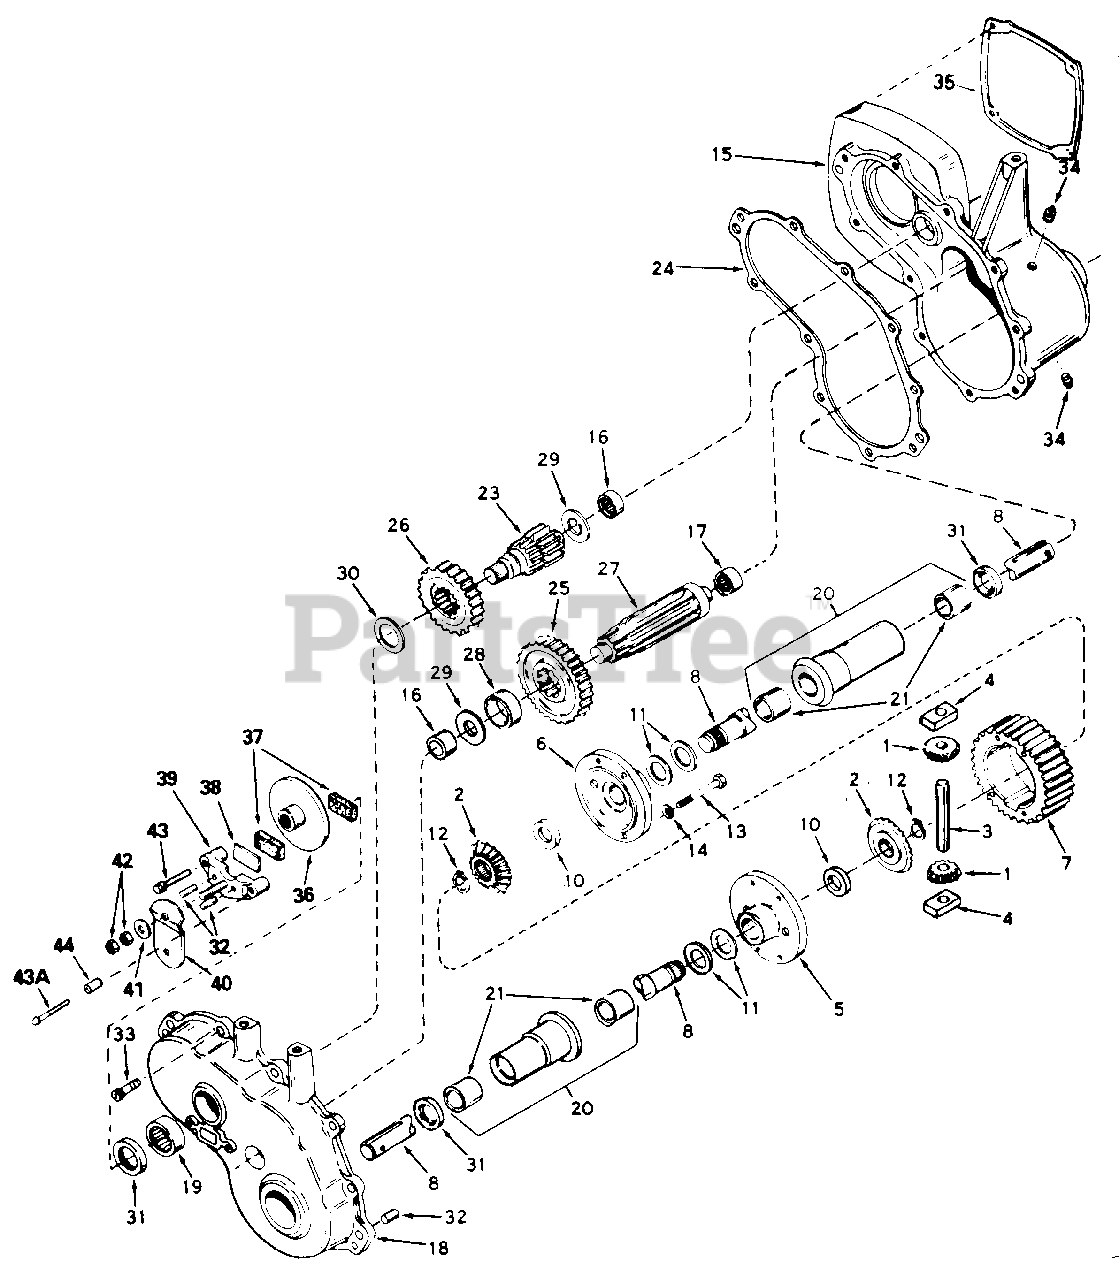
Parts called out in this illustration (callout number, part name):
1	Pinion, Bevel
2	Gear, Bevel
3	Pin, Drive
4	Block, Drive
5	Carrier, Differential
6	Carrier, Differential
7	Gear, Ring
8	Axle (16-1/64" Long)
10	Washer
11	Washer, Thrust
12	Ring, Snap
13	Screw, Hex Hd. 1/4-20 x 21/4
14	Lock Washer, 1/4"
15	Case Ass'y.
16	Bearing, Needle
17	Bearing, Needle
18	Cover Ass'y.
19	Bearing, Needle
20	Housing Ass'y., Axle
21	Bushing
23	Shaft, Brake
24	Gasket, Case to Cover
25	Gear, Output
26	Gear, Idler
27	Shaft, Output
28	Spacer
29	Washer
30	Washer
31	Seal, Oil
32	Pin, Dowel
33	Screw, Hex Hd., Self-Tapping, 1/4-20 x 1
34	Plug, Pipe
35	Gasket
36	Disc, Brake
37	Pad, Brake
38	Plate, Brake Pad
39	Holder, Brake Pad
40	Lever, Brake
41	Washer, Flat
42	Lock Nut 5/16-24
43	Screw, Hex Hd., Self-Tapping, 1/4-20 x 1-1/4
43A	Screw, Hex Hd., Self-Tapping, 1/4-20 x 2-1/4
44	Spacer
